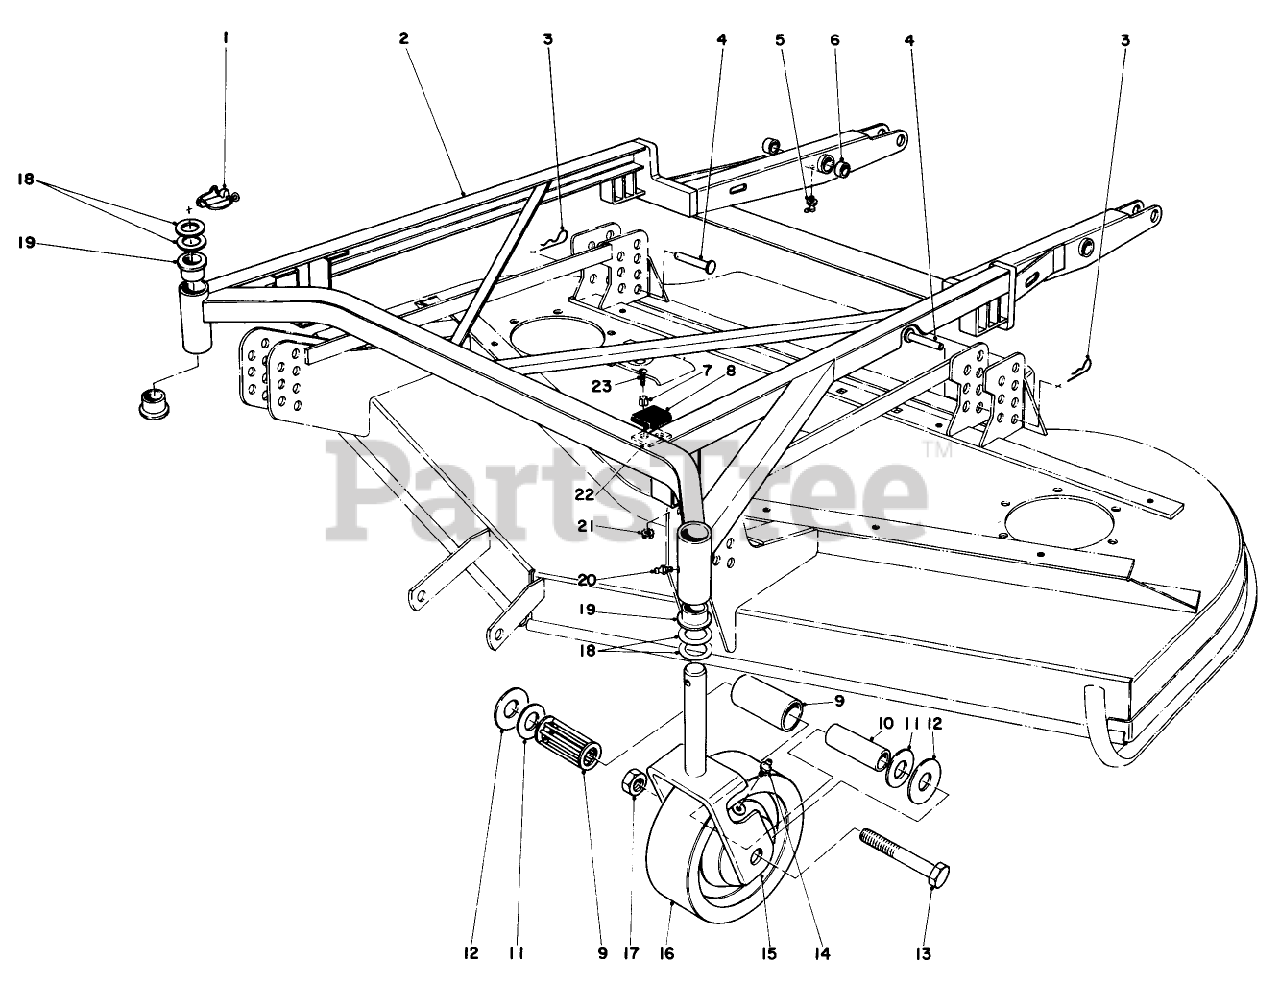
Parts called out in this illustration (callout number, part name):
1	PIN-LYNCH
2	Frame-Deck Suspension (Incl. Ref. #5-6 & 19)
3	PIN-HAIR
4	PIN-CLEVIS
5	FITTING-GREASE, 90 DEG
6	7/8 ID X 1.128 X 7/8 LG BSHG
7	SPACER
8	CUSHION-RUBBER
9	ROLLER BEARING
10	SPANNER BUSHING
11	BEARING RETAINER
12	THRUST WASHER
13	SCREW-HH
14	GREASE FITTING
15	FORK-Castor
16	WHEEL
17	NUT-LOCK
18	WASHER-THRUST
19	Bushing
20	FITTING-GREASE
21	NUT-LOCK, NI
22	SHIM-CUSHION
